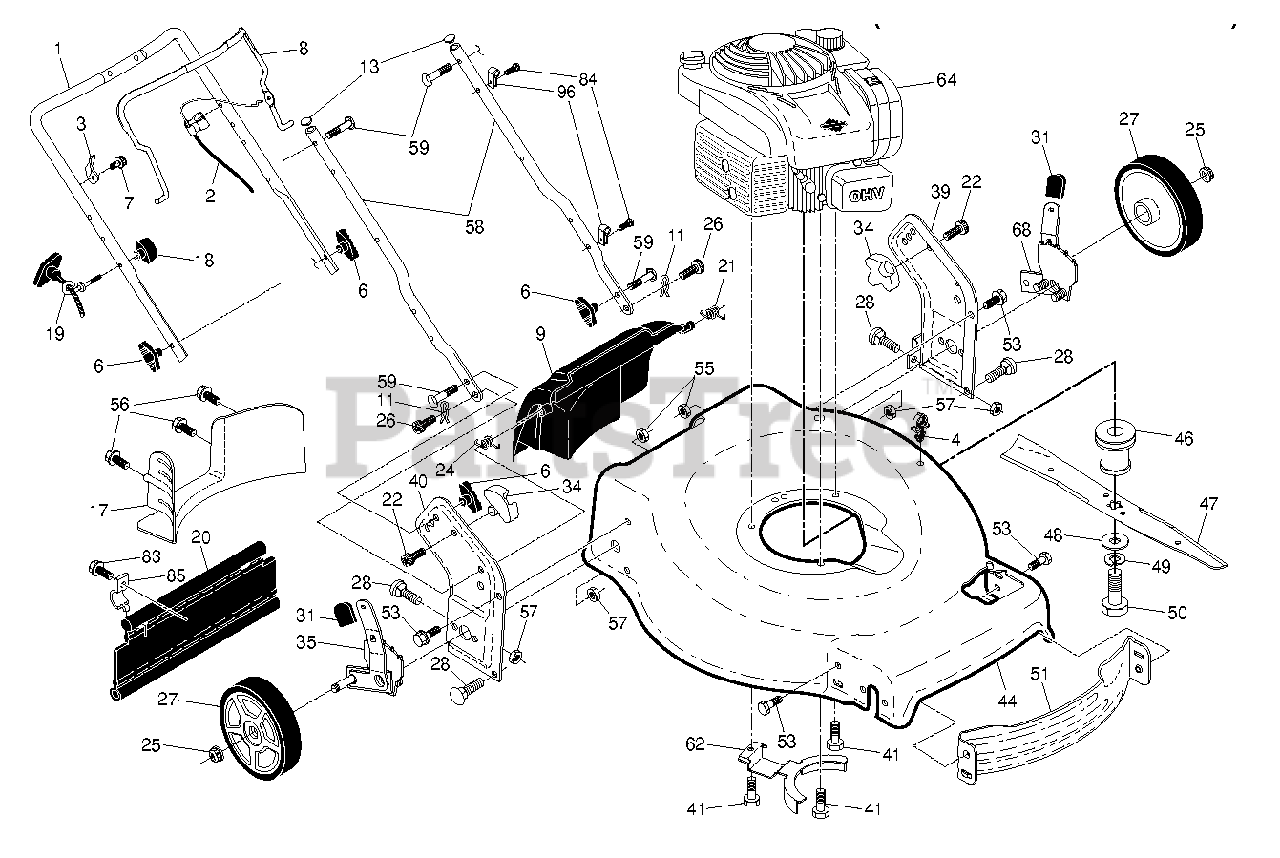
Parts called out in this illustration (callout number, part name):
1	HANDLE.UP.DSTR.FG/RGD.BLACK
2	CABLE.MZR.FGD.PLUS
3	BRACKET.UPSTOP.RT
4	PUSH CLIP
8	BAIL.MZR.STRAIGHT.22+.YELLOW
9	DOOR.REAR.22PLUS.MB.FGD.SAFETY
11	COTTER.HAIRPIN.DOOR/HANDLE.PIV
13	PLUG.PLASTIC.7/8".14-20.GAUGE
17	BAFFLE.22PLUS.FGD.REAR.
18	T-KNOB.NEW ROPE GUIDE
19	Rope Guide, Blk Zinc Chrom
20	SKIRT.REAR.22PLUS.RGD/FGD.NEW
21	SPRING.LH.GRAY
22	SCREW.PAN.HEAD.#10
24	SPRING.RH.GRAY
25	NUT.HEX.FLANGE.3/8-16.LOCKNUT
26	SCREW,DOOR/HANDLE.PIVOT
31	SELECTOR KNOB
34	BRACKET.GRASSBAG.ATTACHING.BLK
35	ADJUSTER.ASM.9POS.LW.RR/RGD.
39	Handle Bracket Assembly, LH 22+ Black
40	Handle Bracket Assembly, RH 22+ Black
41	BOLT 3/8-16X1-1/8
44	KIT.HSG.22 REAR .FGD.421.TRI
46	ADAPTOR.BLADE.7/8".STAR
47	BLADE.22PLUS
48	WASHER,HARDEN
50	SCREW, HEX HD 3/8-24 X 1-3/8
51	BAFFLE.FRONT.22.PLUS
53	BOLT.5/16HEX.WHS.HD
55	NUT.HEX.FLANGE.1/4
56	SCREW.HX.13X.750
57	NUT.FLANGE.5/16
58	HANDLE.LOWER.22+BT.2PC.BLK
59	BOLT, HANDLE 5/16-18X1.75
62	BRACKET.ENG/BELTKEEPER
68	ADJUSTER.ASM.9POS.LW.RL/RGD.FR
83	TAPPING SCREW
84	FASTENER.PUSH.O.250X0.783
85	BRACKET.SKIRT.22+.BZP
96	CLIP.CABLE.BLK
